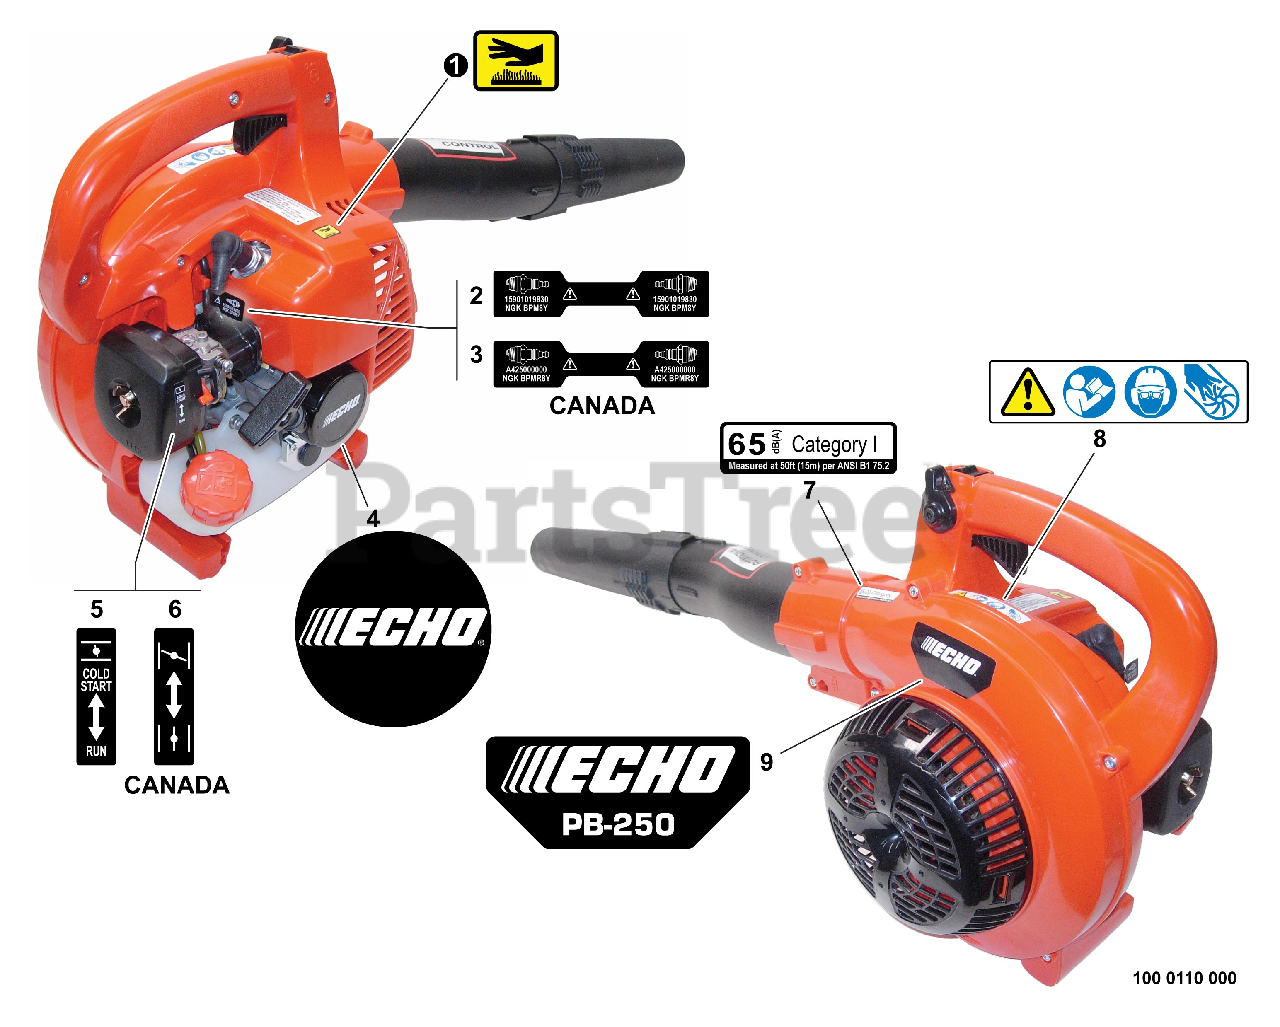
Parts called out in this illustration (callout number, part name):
1	LABEL - HOT SURFACE
2	LABEL - SPARK PLUG -- BPM-8Y
3	LABEL - SPARK PLUG -- BPMR-8Y
4	LABEL - ECHO
5	LABEL - CHOKE
6	LABEL - CHOKE
7	LABEL - NOISE 65dB(A) CAT I
8	LABEL - CAUTION
9	LABEL - MODEL PB-250
